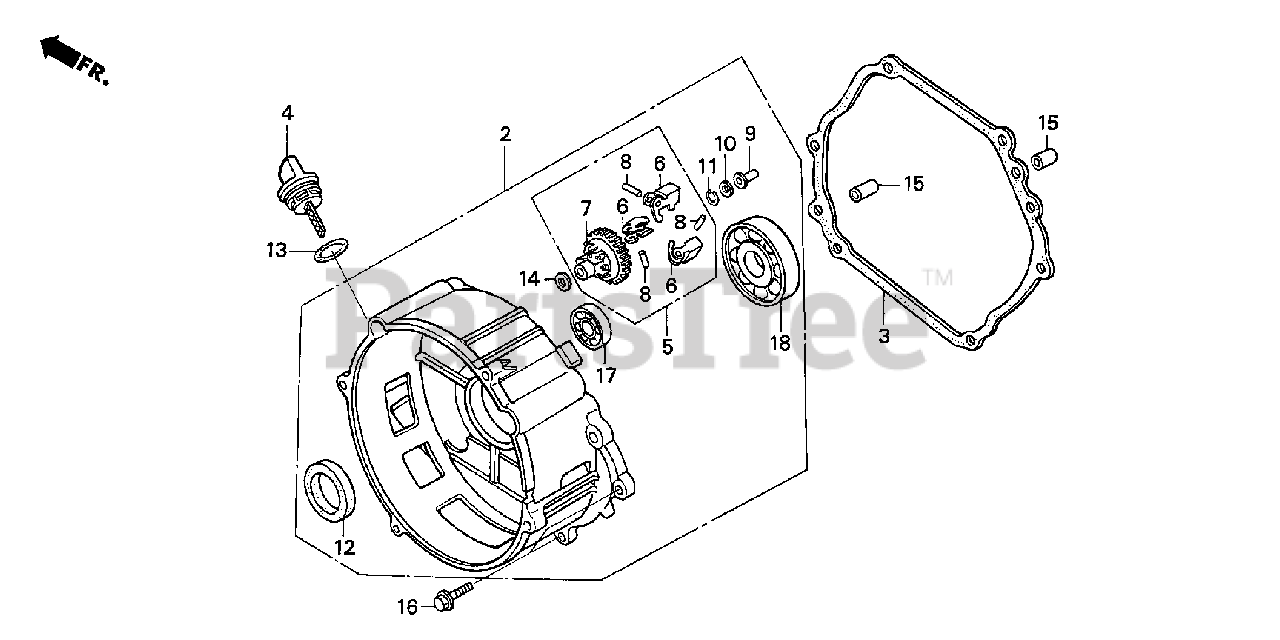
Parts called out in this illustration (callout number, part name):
2	COVER ASSY., CRANKCASE (E-TYPE)
2	COVER ASSY., CRANKCASE
3	GASKET, CASE COVER
4	CAP, OIL FILLER
5	GOVERNOR ASSY.
6	WEIGHT, GOVERNOR
7	HOLDER, GOVERNOR WEIGHT
8	PIN, GOVERNOR WEIGHT
9	SLIDER, GOVERNOR
10	WASHER (6X16)
11	CLIP, GOVERNOR HOLDER
12	OIL SEAL (35X52X8)
13	O-RING (26X2.7)
14	WASHER, PLAIN (6MM)
15	PIN, DOWEL (8X12)
16	BOLT, FLANGE (8X40)
17	BEARING, RADIAL BALL (6202)
18	BEARING, RADIAL BALL (6207)
